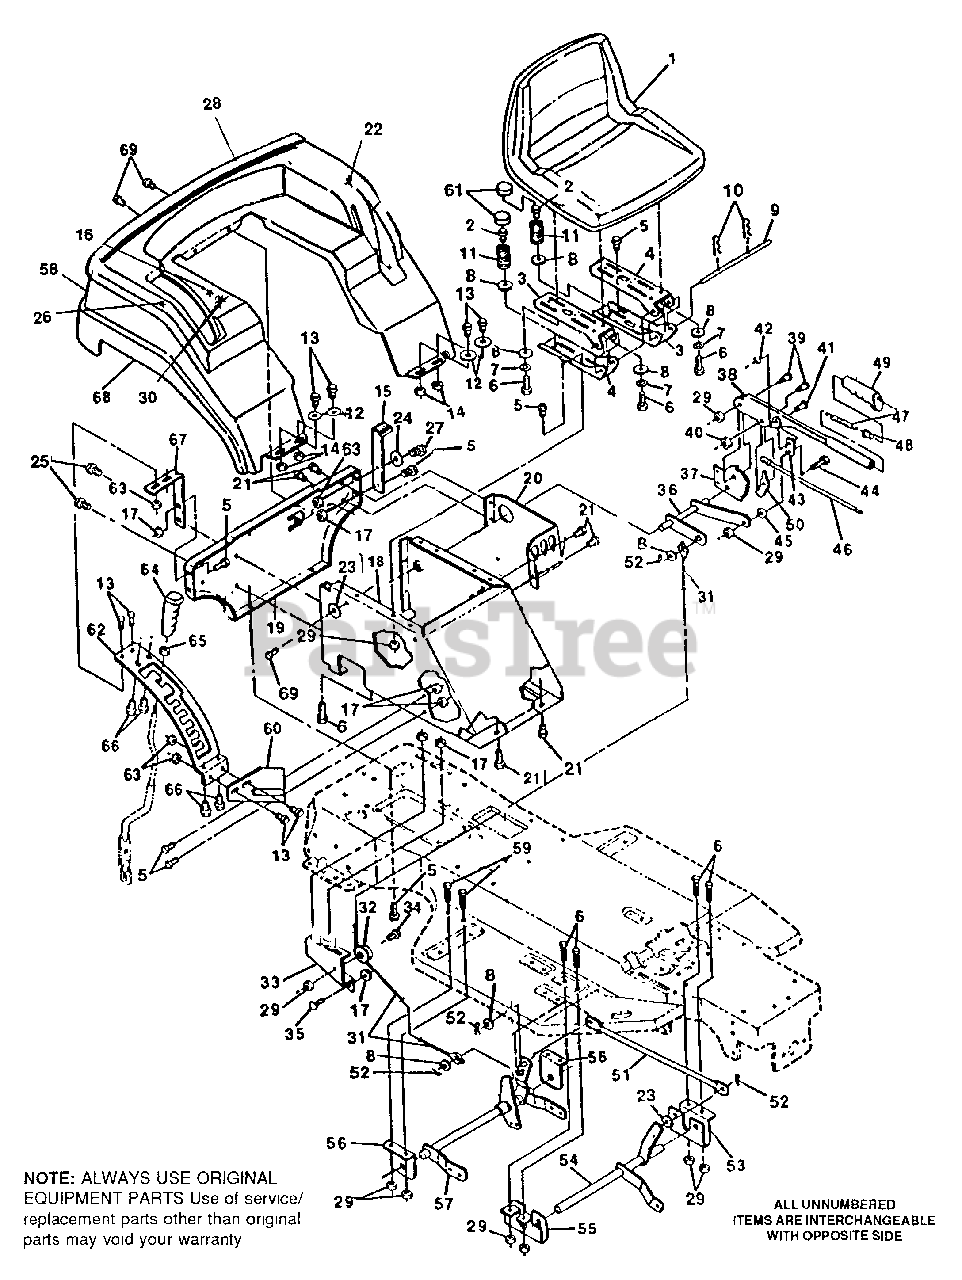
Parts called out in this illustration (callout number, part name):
2	Screw, 5/16 18 x .63
3	Channel, Seat L.H.
4	Channel, Seat R.H.
5	Screw, Hx Hd, Wd Fl 5/16-18 x 3/4 In.
6	Screw, Hx Hd, 5/16-18 x 3/4 In.
7	Washer, Lock 5/16 In.
8	Washer, Flat, 11/32 In.
9	Rod, Seat Support
10	Hair Pin, .073 Dia. x 1.13 In.
11	Seat Spring
12	Washer, Flat, 9/32 In.
13	Screw, Hx Hd, 1/4-20 x 5/8 In.
14	Nut, Lock, 1/4-20 Thd.
15	Fender Support, L. H.
16	Decal, Husqvarna U.S.A.s
17	Nut, Hx, Wd Fl, Lk 5/16-18 Thd.
18	Seat Support
19	Support, Fender & Seat
20	Bracket, Support Engage
21	Screw, Hx Wshr Hd Tap, 5/16-18 x 1/2 In.
22	Decal, Decal Height EURO Elec/Clutch
23	Flatwasher, 13/32 In.
24	Flatwasher
25	Screw, Tap, 5/16-18 x 7/8 1
26	Decal, Gear Shift Neutral EURO
27	Screw, 1/4-20 x 3/4 In
28	Decal, Fender Rear, Hood Husq.
29	Nut, Hx Ctrlk, 5/16-18 Thd.
30	Decal, Gear Shift 6 Speed EURO
31	Cable, Deck Lift
33	Assembly, Pulley Bracket
34	Shoulder Bolt, 5/16-18 Thd.
35	Bolt, Carriage, 5/16-18 x 5/8 In.
36	Assembly, Upper Shaft
37	Quadrant
38	Lift Lever
39	Shoulder Bolt, 5/16-18 Thd.
40	Nut, Hx Wd Fl Lk 5/16-18 Thd.
41	Clevis Pin
44	Shoulder Bolt, 5/16-18 Thd.
46	Actuator Rod
47	Spring, Height Adjust
48	Knob, Height Adjust
49	Handle, Lift
50	Pawl, Height Adjust
52	Cotter Pin
53	Bracket, L.H. Front Hanger
54	Assembly, Front Lift Shaft
55	Bracket, R.H. Front Hanger
56	Bracket, Hanger
57	Assembly, Rear Lift Shaft
58	Decal Shift-n-go ( Husq. ).
59	Screw, Hx Hd, 5/16-18 x 5/8 In.
60	Support, Shift Plate
61	Cover, Seat Spring
62	Quadrant
63	Nut, Hx, Wd Fl Lk, 1/4-20 Thd.
65	Nut, Hx 3/8-16 Thd.
66	Screw, Hx Hd, Tap #10 x 1/2 In.
67	Fender Support, R. H.
69	Screw, Hx, Wshr Hd, Tap 1/4-20 x 5/8 In.
